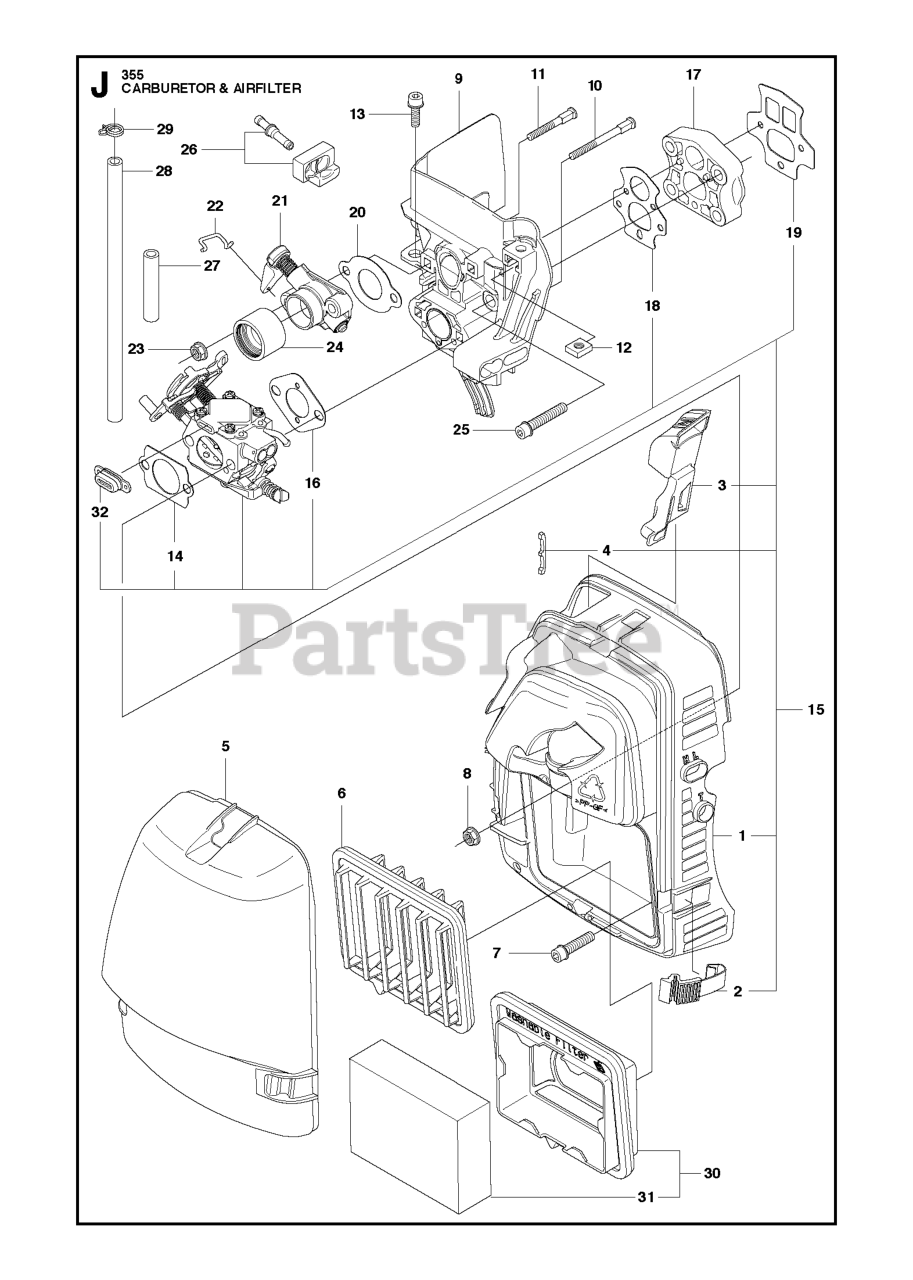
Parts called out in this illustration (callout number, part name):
1	FILTER HOLDER ASSY.
3	CHOKE CONTROL
5	FILTER COVER
6	FILTER
9	INSULATION WALL
15	CARBURETOR KIT
21	VALVE HOUSING
24	INLET PIPE
25	SCREW IHSCFM
26	GROMMET
27	SUCTION HOSE
28	RP FUEL HOSE
29	HOSE CLAMP
30	FILTER
31	FILTER
32	SEALING PLUG
